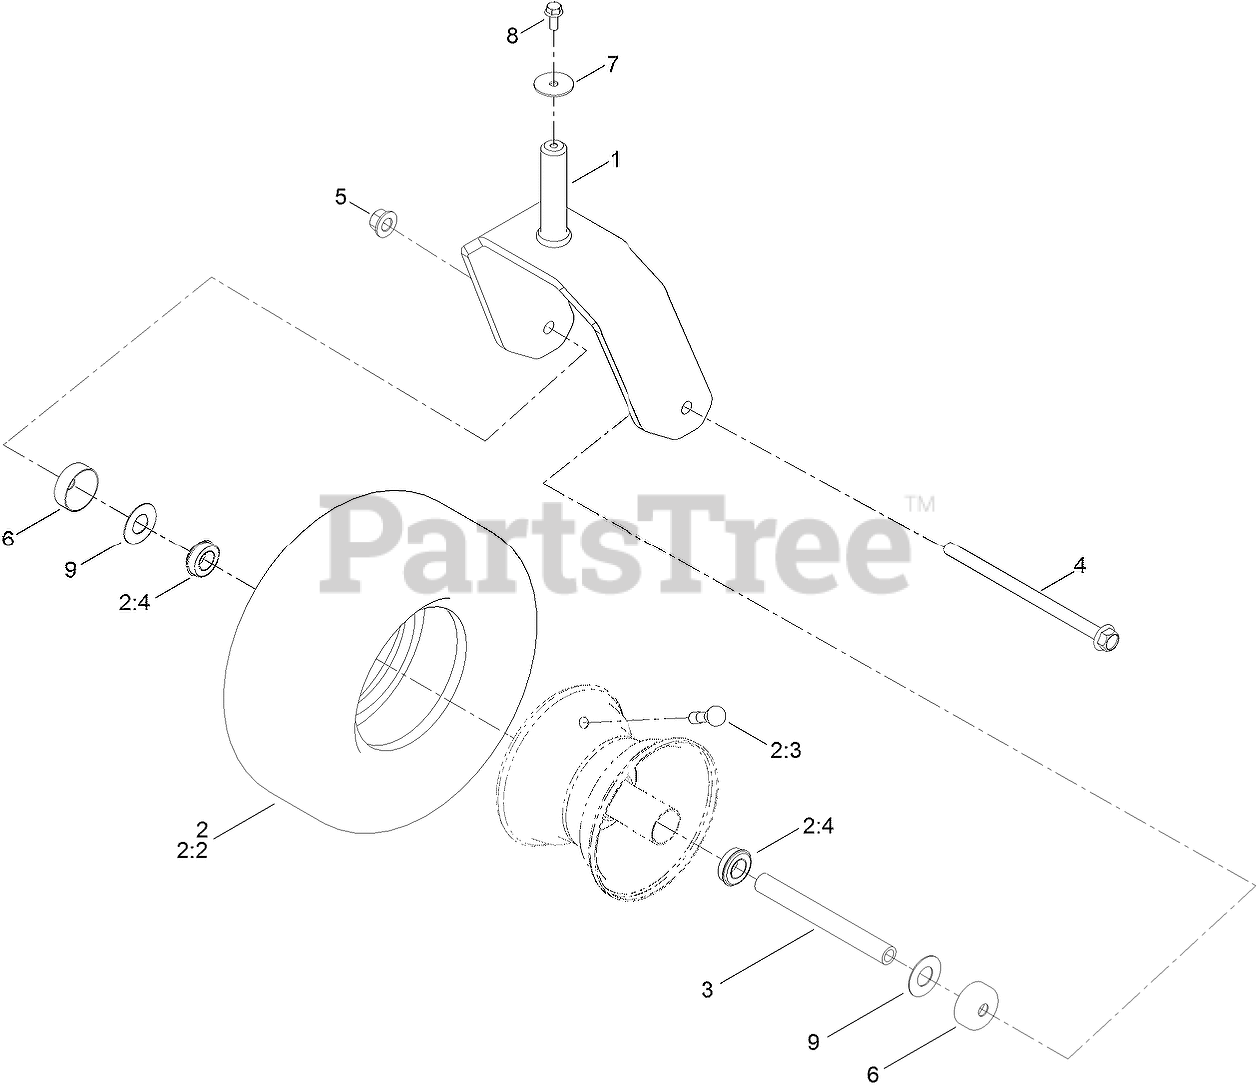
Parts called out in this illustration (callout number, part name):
1	FORK-CASTER
2	TIRE AND WHEEL ASM
2:4	BEARING
3	SPANNER-WHEEL
4	SCREW-HHF
5	NUT-LOCK
6	GUARD-SEAL
7	WASHER-FLAT
8	SCREW-HHF
9	WASHER
